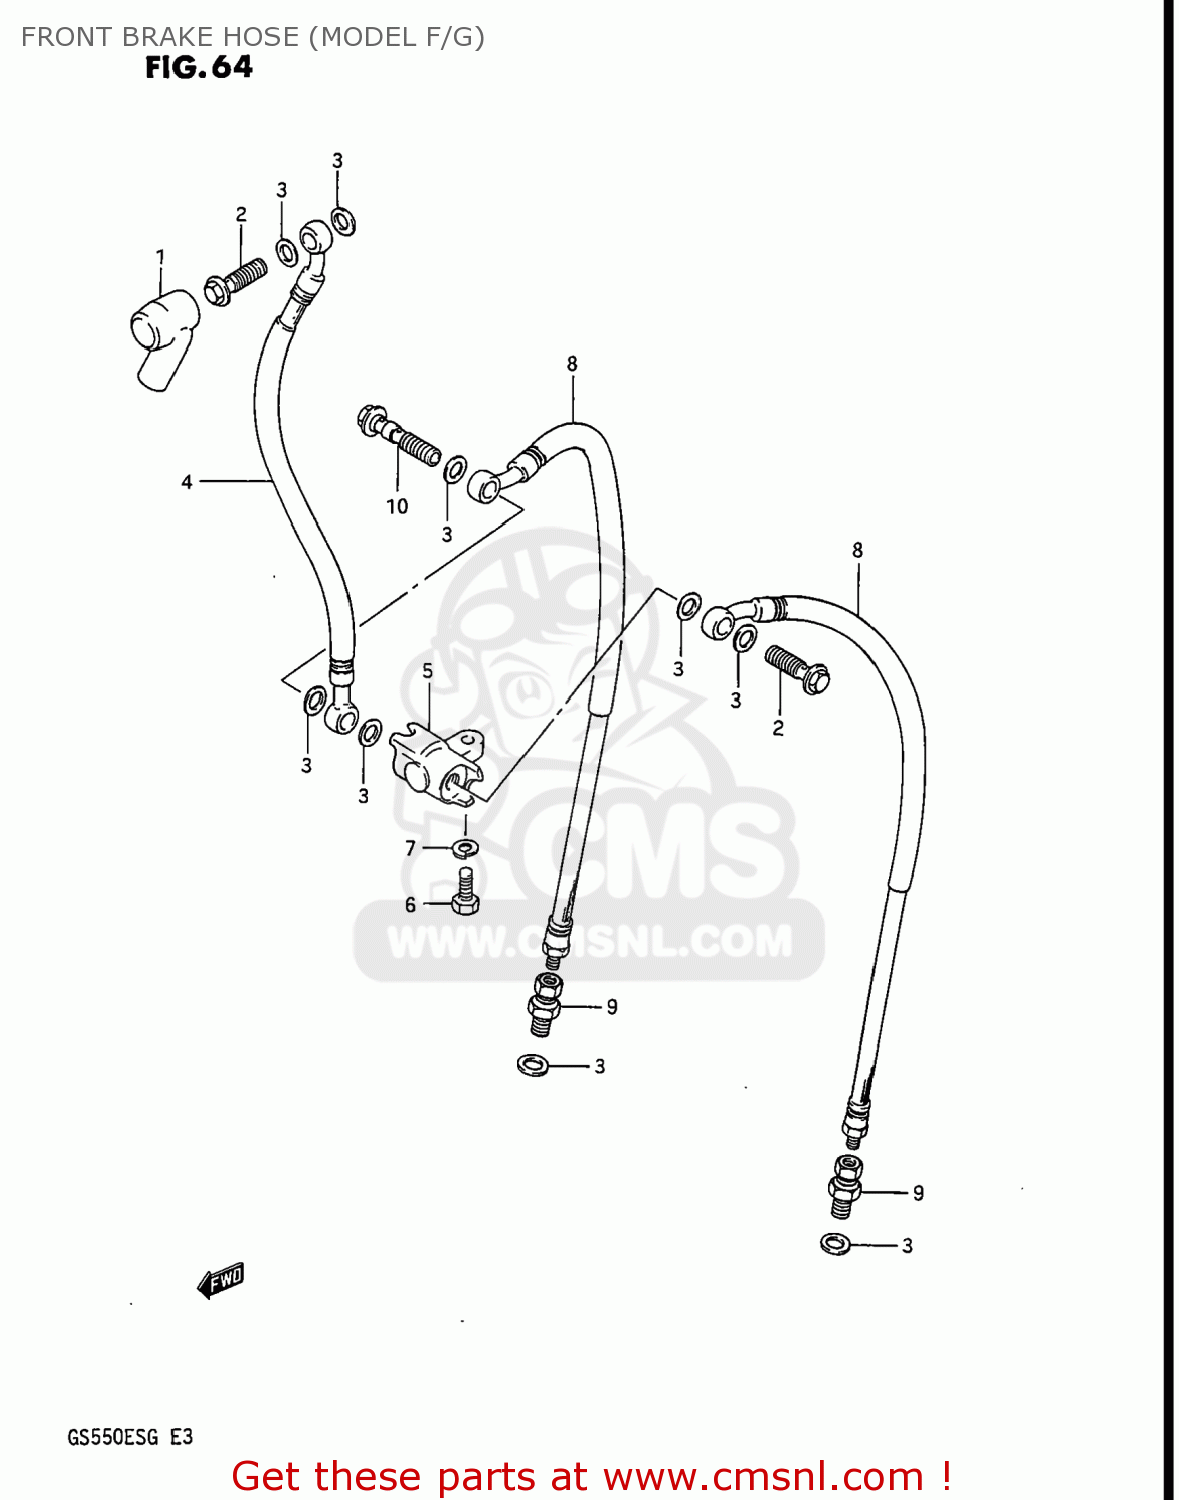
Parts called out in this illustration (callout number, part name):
1	BOOT,MASTER CYLINDER
2	BOLT UNION
3	WASHER(10X15X1.5)
4	HOSE,FRONT BRAKE
5	JOINT,BRAKE HOSE
6	BOLT
7	WASHER,LOCK
8	HOSE,BRAKE NO.2
9	ADAPTER,BRAKE HOSE
10	BOLT UNION
